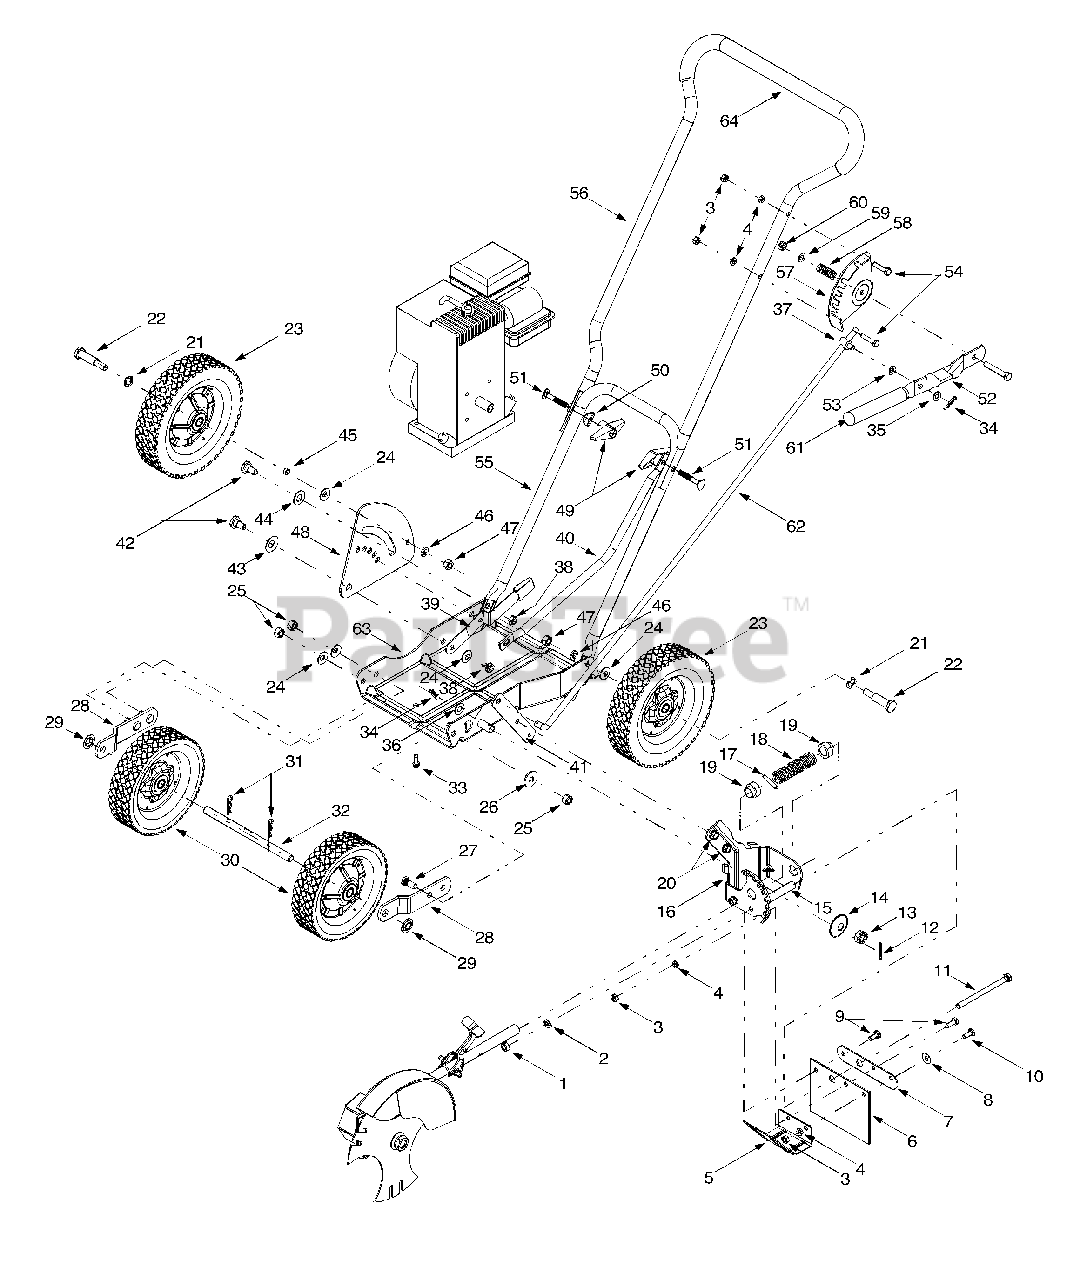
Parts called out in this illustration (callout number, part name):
1	Hex Nut, 5/16-18
2	Lock Washer, 5/16
3	Hex Nut, 1/4-20
4	Lock Washer, 1/4
7	Flap Bracket, 1.12 x 5.5
8	Flat Washer, .283 x .75 x .030
9	Hex Screw w/ Nose, 1/4-20 x .85
10	Hex Screw, 1/4-20 x .62
11	Hex Screw, 5/16-18 x 4.5
12	Cotter Pin, 1/8 x 1.0
13	Slotted Hex Nut, 1/2-20
14	Sphere Washer, .531 x 1.6 x .045
15	Spacer, .38 x .50 x 3.75
18	Compression Spring
19	Shoulder Spacer, .635 x .620
20	Self-Tapping Scr, 5/16-18 x .50
21	Wave Washer, .510 x .75 x .017
22	Shoulder Screw, .498 x 1.45
23	Wheel w/ Ball Bearing, 8 x 1.75
24	Spring Washer, .401 x .871 x .063
25	Hex Nut, 3/8-24
26	Bell Washer, .396 x 1.14 x .095
27	Round Head Ribbed-Neck Bolt,3/8-24 x .89
30	Wheel w/ Ball Bearing, 7 x 1.75
31	Internal Cotter Pin, .08 x 1.42
32	Front Axle, .50 x 7.98
33	Self-Tapping Screw, 3/8-16 x 1.0
34	Internal Cotter Pin, .072 x 1.0
35	Flat Washer, .330 x .630 x .0635
36	Flat Washer, .406 x .810 x .051
37	Adjustment Ferrule
38	Center Lock Nut, 3/8-24
39	Curb Adjustment Lever Assembly
40	Support Strut, 15.91
41	Spindle Extension Arm
42	Shoulder Screw, .498 x .250
43	Bell Washer, .51 x 1.14 x .040
44	Flat Washer, .51 x 1.0 x .060
45	Spacer, .376 x .625 x .22
46	Lock Washer, 3/8
47	Hex Nut, 3/8-16
50	Saddle Washer, .320 x .93
51	Curved Head Carriage Bolt,5/16-18 x .75
52	Blade Clutch/Depth Control Lever
53	Spring Washer, .317 x .625 x .099
54	Hex Cap Screw, 5/16-18 x 2.0
55	Lower Handle
56	Upper Handle (Loop Style)
58	Compression Spring, .55 x 1.37
59	Flat Washer, .344 x .62 x .030
60	Hex Lock Nut, 5/16-18
61	Foam Grip (Blade Clutch Lever)
62	Clutch Rod, 3/8 x 33.5
